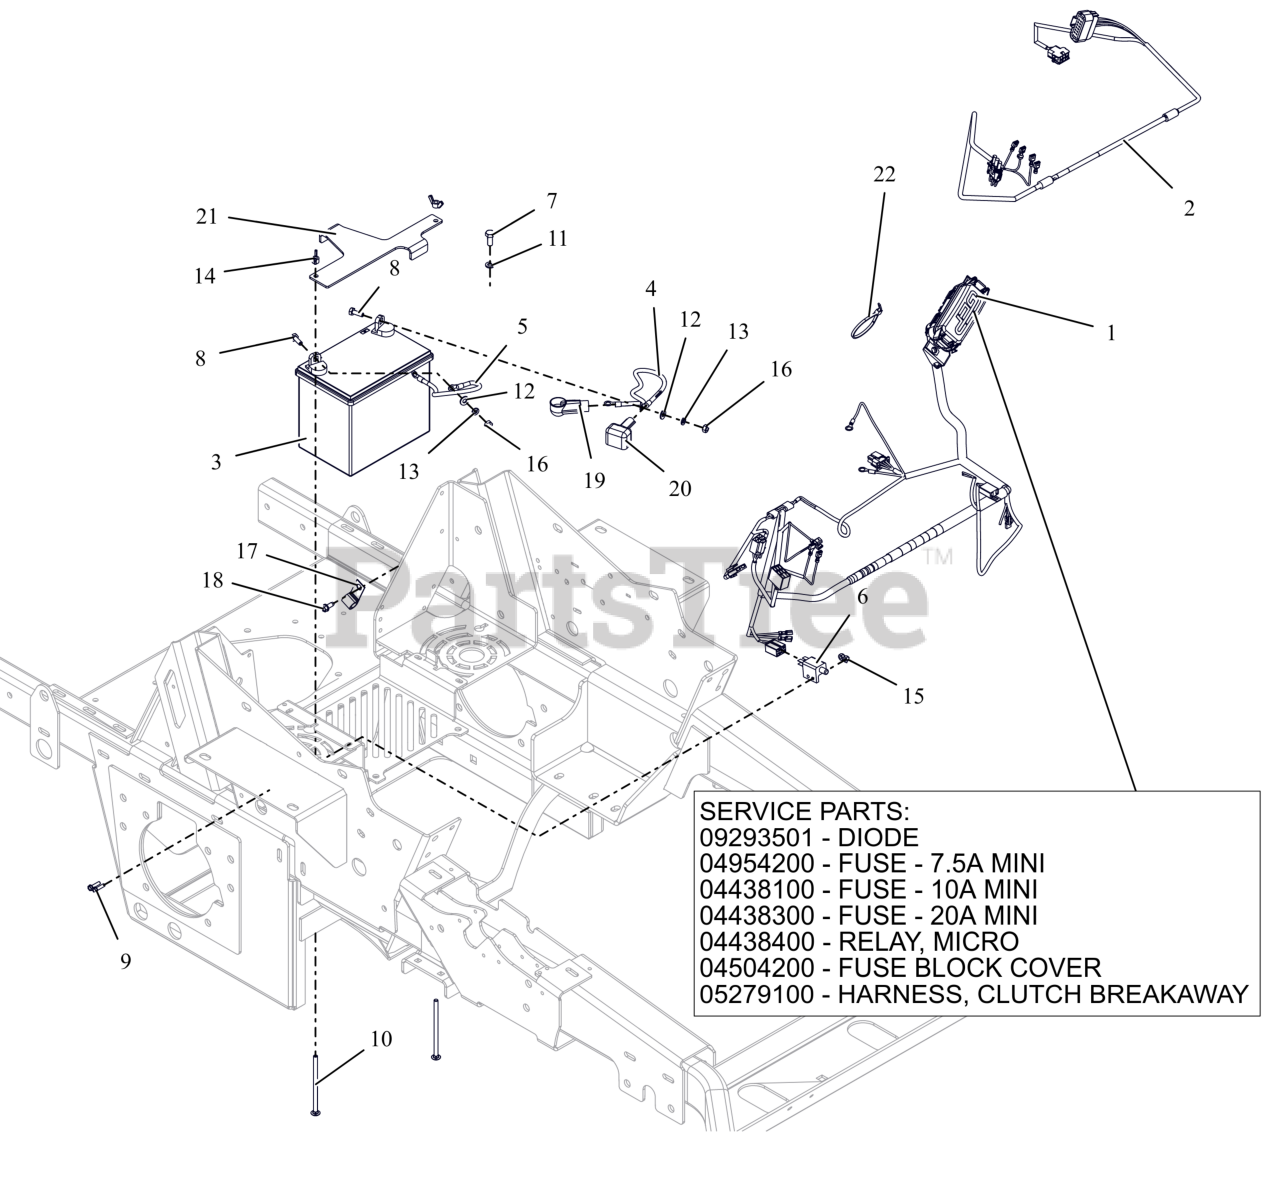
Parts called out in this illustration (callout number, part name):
1	HARNESS- WIRE PT300 MAIN
1	DIODE, CONNECTOR SHELL
1	FUSE, 7.5 AMP MINI-ATC
1	FUSE,10 AMP MINI-ATC
1	FUSE,20 AMP MINI ATC
1	RELAY,MICRO5 TERML W/RESISTOR
1	COVER, HARNESS FUSE/RELAY MOD
1	HARNESS, CLUTCH BREAKAWAY
2	HARNESS- EFI ENG ADAPTER PT300
3	BATTERY, 300 CCA 10U1L
4	CABLE, STARTER 13.00"
5	CABLE-GROUND .25 X 13.00 X .31
6	SWITCH- DOUBLE POLE N.O./N.O.
7	BLT, HEX M8-1.25X20 G8.8 ZCC
8	BLT, HEX .25-20X.75 G5 ZCC
9	BLT, HWH #10-24X.75 ZCC
10	BLT, RHSN .25-20X4.50 G5 ZCC
11	WSHR,LK-REG .312X.078 ZCC
12	WSHR,FLT .281X.625X.065 ZCC
13	WSHR,LK-REG .250X.062 ZCC
14	NUT, LK-WING .25-20 ZCC
15	NUT-LK-NYL #10-24 G2 ZCC
16	NUT-STD .250-20 G2 ZCC
18	SCR,TAP .25-20X.625 HWH ZCC
19	BOOT, .65ID POS
20	INSULATOR
21	HOLDDOWN- BATTERY
22	CABLE TIE, .15 X 8.50
